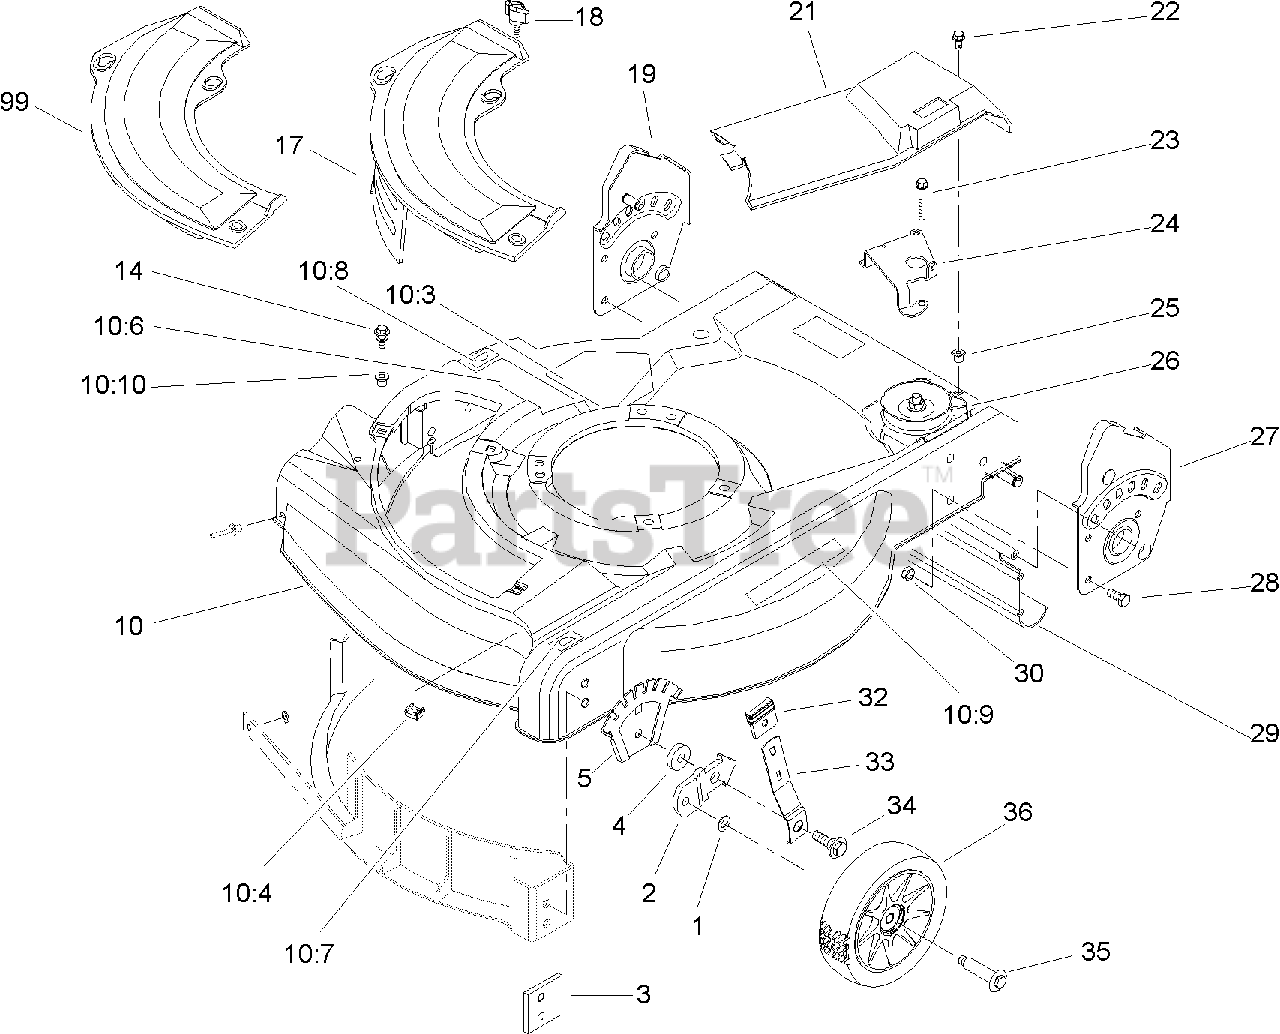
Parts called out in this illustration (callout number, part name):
2	BRACKET-HEIGHT ADJUSTMENT, WHEEL
3	PLATE-BAFFLE
4	WASHER-WHEEL
5	PLATE-HEIGHT, ADJUSTMENT
10	DECK ASM
10:3	DECAL-DANGER
10:4	NUT-CAGE
10:6	DECAL-WARNING
10:7	DECAL-HOC, LH
10:8	DECAL-HOC, RH
10:9	DECAL-WARNING
10:10	NUT-CLIP
14	SCREW-SEMS
17	PLATE-MULCH
19	RH BRACKET ASM
21	COVER-DRIVE
22	SCREW-THREAD CUT
23	SCREW-HWHTF
24	GUIDE-TRANSMISSION
25	NUT-CLIP
26	GEAR CASE ASM
27	LH BRACKET ASM
28	SCREW-HH
29	SHIELD-TRAILING
30	NUT-LOCK, NI
32	KNOB-LEVER, HEIGHT ADJUSTMENT
33	ARM-FRONT SPRING
34	BOLT-SHOULDER
35	BOLT-SHOULDER
36	WHEEL AND TIRE ASM
99	PLATE-OPENING, CHUTE
